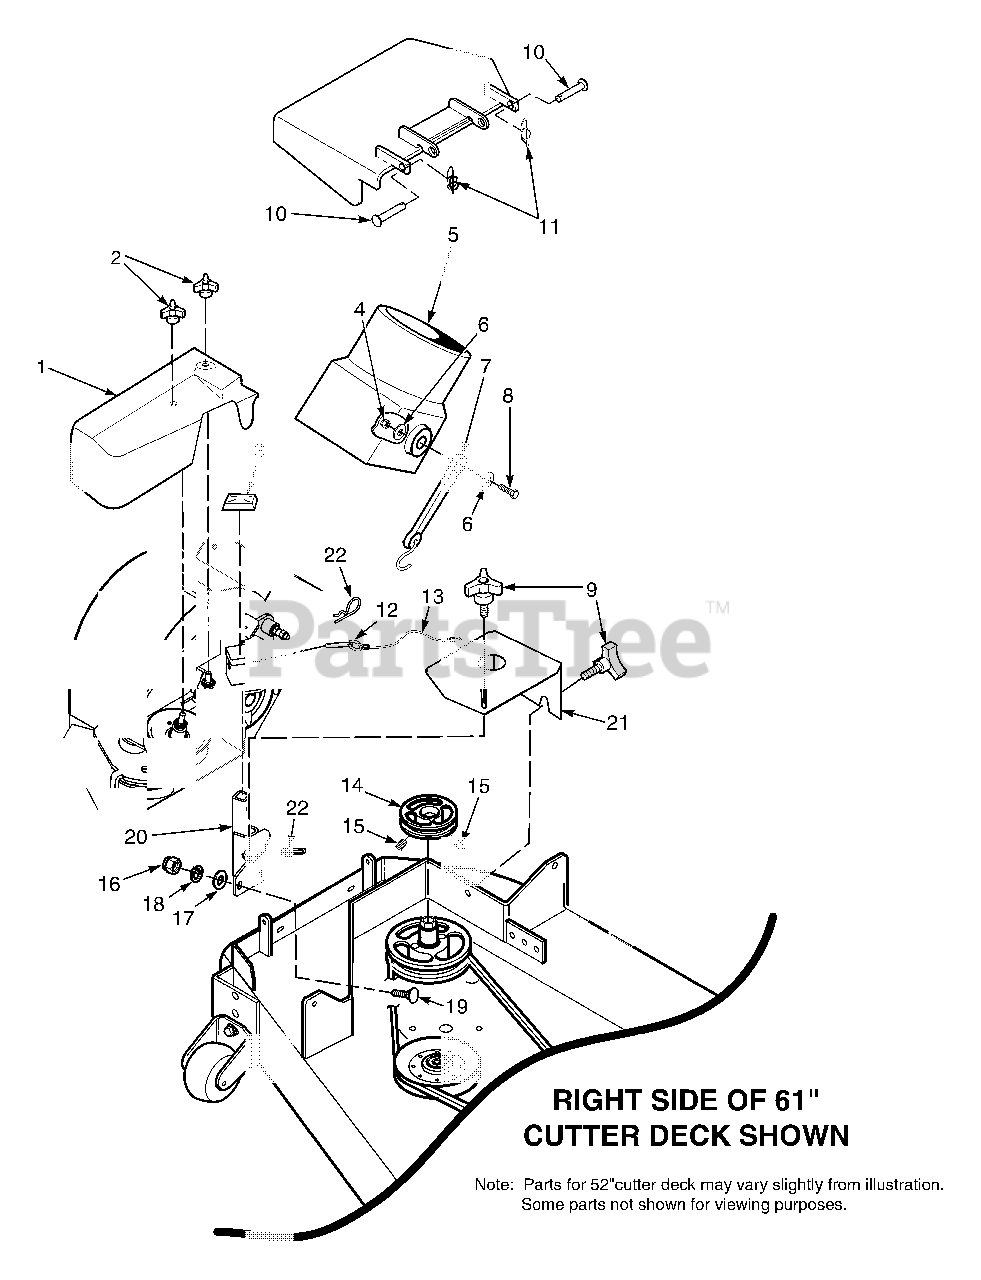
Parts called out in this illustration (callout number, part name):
1	Belt Cover, GC-STWC - 61"
2	Wingnut, Plastic 3/8 Small
3	Cap, Square Vinyl
4	Nut, Elastic Stop 1/4-20
5	Adapter, Blower GC-STT
6	Flatwasher, 1/4-.312 x .750 x .065
7	Rubber Strap 7-3/4"
8	Bolt, Hex Head 1/4-20 x 1-1/4"
9	Knob W/Stud, 3/8-16 x 1-1/4"
10	Clevis Pin, 5/16 x 1-1/2"
11	Pin, Rue Cotter 5/16 Dia.
12	Pin, Ring 1/2 x 2-1/4"
13	Lanyard
14	Pulley, 5-1/2" for 61" Deck
15	Setscrew, 5/16-18 x 3/8"
16	Nut, Elastic Stop 1/2-13
17	Lockwasher, 1/2"
18	Flatwasher, 1/2-.531 x 1.062 x .095
19	Bolt, Hex Head 1/2-13 x 1-1/2" Grade 5
20	Mounting Post Weldment, Blower - 61"
21	Belt Cover, GC-STWC-61
22	Hair Pin Cotter, .177 x 3-1/4"
